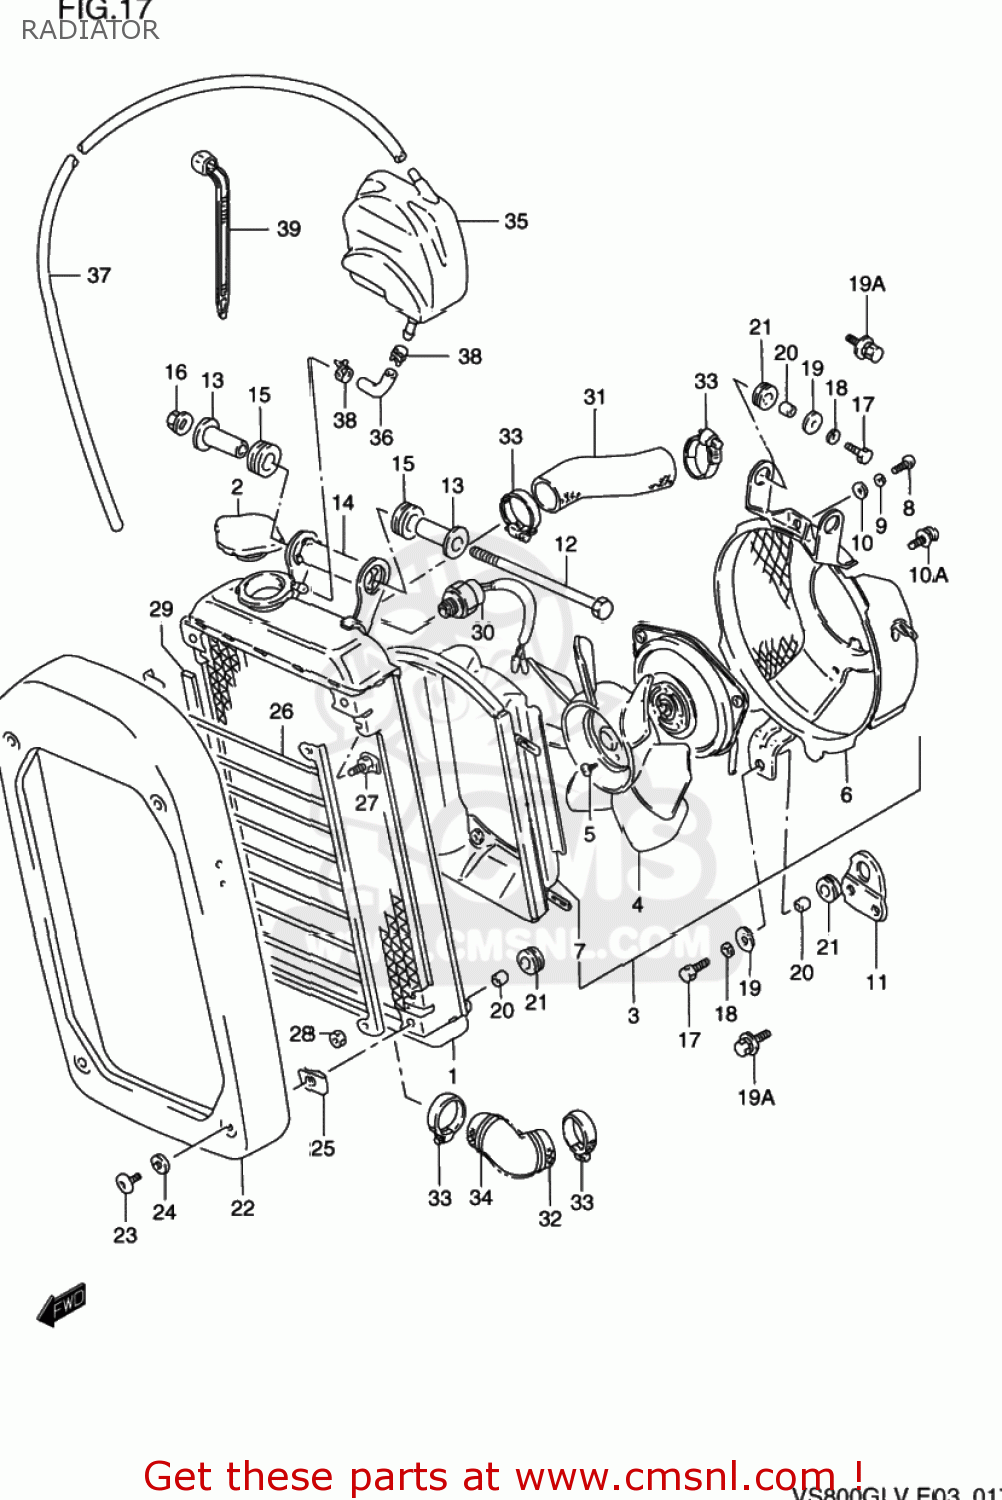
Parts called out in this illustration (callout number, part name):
1	RADIATOR ASSY,WATER
2	CAP,RADIATOR
3	FAN ASSY,RADIATOR
4	FAN
5	BOLT
6	SHROUD,FAN
7	DUCT,FAN
8	SCREW 5X10
9	LOCK WASHER
10	WASHER
10A	SCREW
11	BRACKET,RADIATOR FAN
12	BOLT 10X135
13	SPACER,RADIATOR CUSHION NO.2
14	SPACER,RDTR CUSH NO.2 OUTER
15	CUSHION
16	NUT 10MM
17	BOLT 6X16
18	WASHER,LOCK
19	WASHER (6.5X18X1.6)
19A	BOLT
20	SPACER (6X9X8)
21	CUSHION
22	COVER,RADIATOR
23	SCREW(6X10)
24	WASHER (6.2X14X2)
25	NUT,RADIATOR COVER
26	BUMPER,RADIATOR
27	BOLT
28	NUT
29	CUSHION,RADIATOR BUMPER
30	SWITCH,RADIATOR FAN
31	HOSE,RADIATOR INLET
32	HOSE,RADIATOR
33	CLAMP
34	SPRING
35	TANK,RESERVOIR
36	HOSE,RESERVE TANK INLET
37	HOSE,RESERVOIR TANK OUTLET
38	CLIP
39	CLAMP(L:125)
